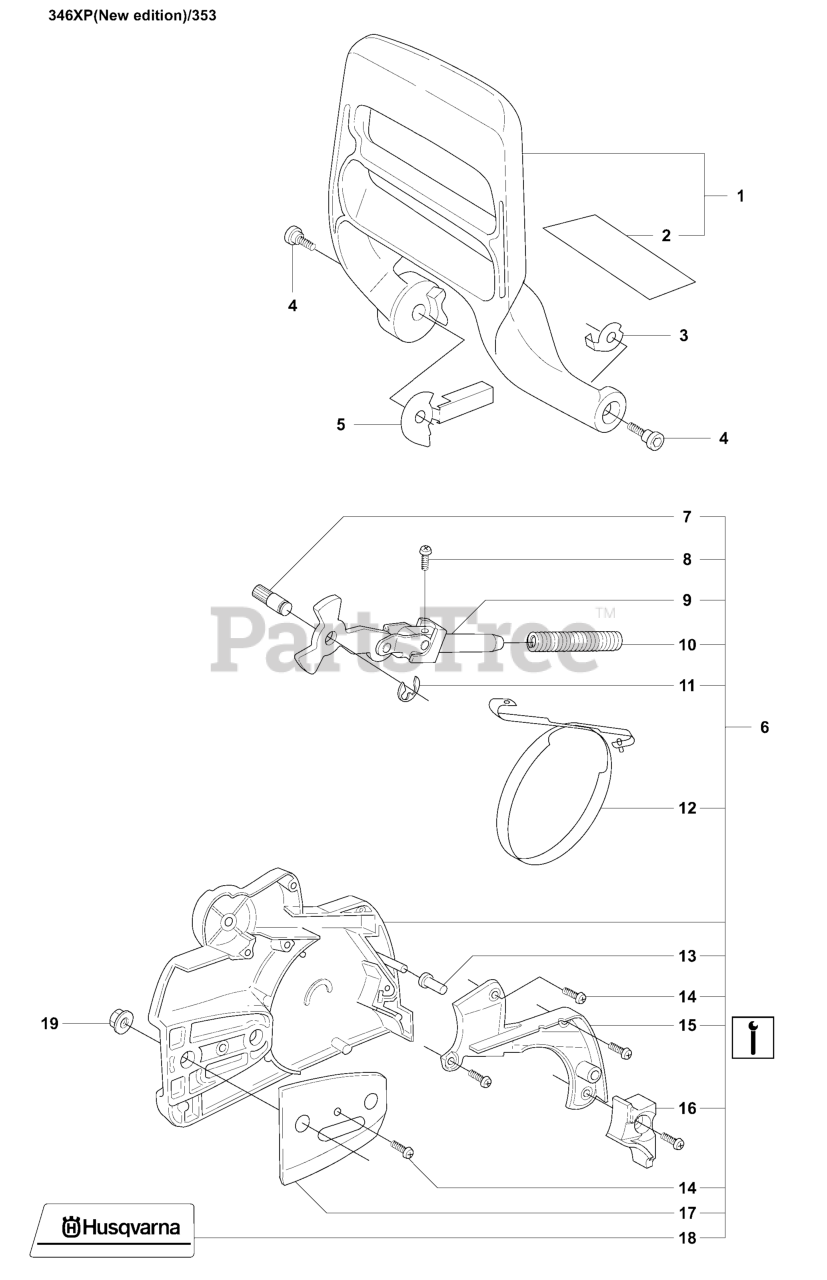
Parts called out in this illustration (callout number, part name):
1	CHAINBRAKE HANDLE
2	PROTECTOR
4	SCREW
6	CHAIN BRAKE ORANGE
6	CHAIN BRAKE SILVER
12	BRAKE BAND
19	NUT M8 FLANGE
